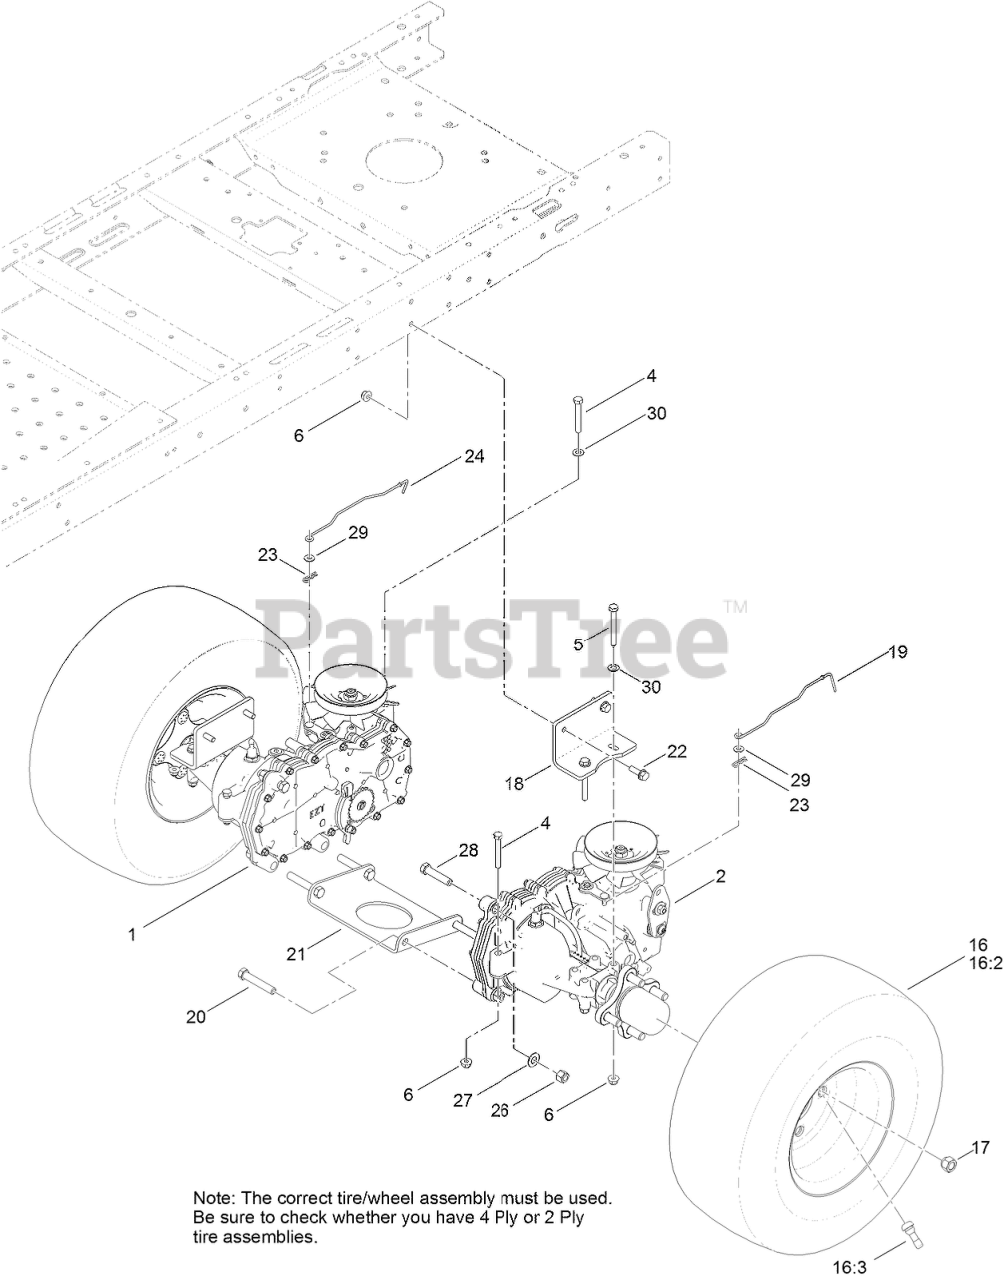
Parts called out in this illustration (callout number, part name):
1	RH HYDRO TRANSAXLE ASM
2	LH HYDRO TRANSAXLE ASM
4	SCREW-HH
5	SCREW-HH
6	NUT-HF, NI
16	4 PLY WHEEL AND TIRE ASM
16	2 PLY TIRE AND WHEEL ASM
16:2	TIRE-4 PLY
16:2	TIRE-2 PLY
16:3	STEM-VALVE
17	NUT-LUG
18	MOUNT-HYDRO
19	ROD-BYPASS, LH
20	SCREW-HH
21	PLATE-CROSS, HYDRO
22	SCREW-HHF
23	PIN-COTTER
24	ROD-BYPASS, RH
26	NUT-LOCK, NI
27	WASHER-FLAT
28	SCREW-HH
29	WASHER
30	WASHER-PLAIN
